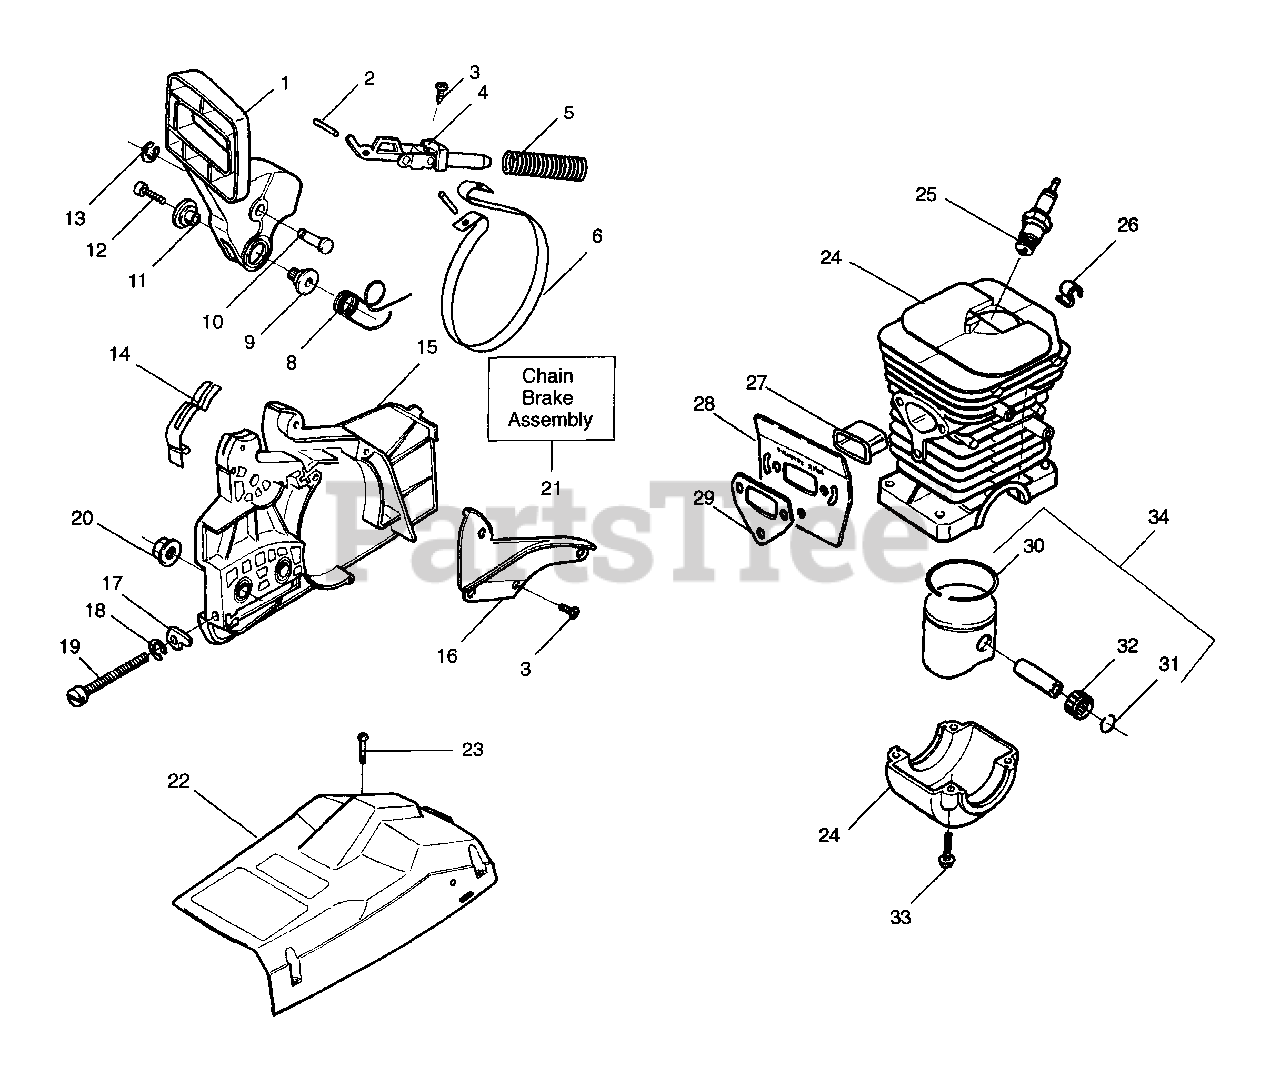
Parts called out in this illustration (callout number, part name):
1	Handguard
2	Straight Pin
3	Screw
4	Front and Rear Link Assembly
5	Chain Brake Spring
6	Brake Band
8	Handguard Spring
9	Left Pivot Sleeve
11	Right Pivot Sleeve
14	Position Spring
15	Clutch Cover
16	Chain Brake Cover
17	Bar Adjusting Pin
21	Chain Brake Assembly
22	Cylinder Shield Ass' y.
24	Cylinder Kit
25	Spark Plug (RCJ-7Y)
27	Heat Insulator
28	Muffler-Plate
29	Muffler Gasket
30	Piston Ring
31	Piston Pin Retainer
32	Piston Pin Bearing
34	Piston Ring
